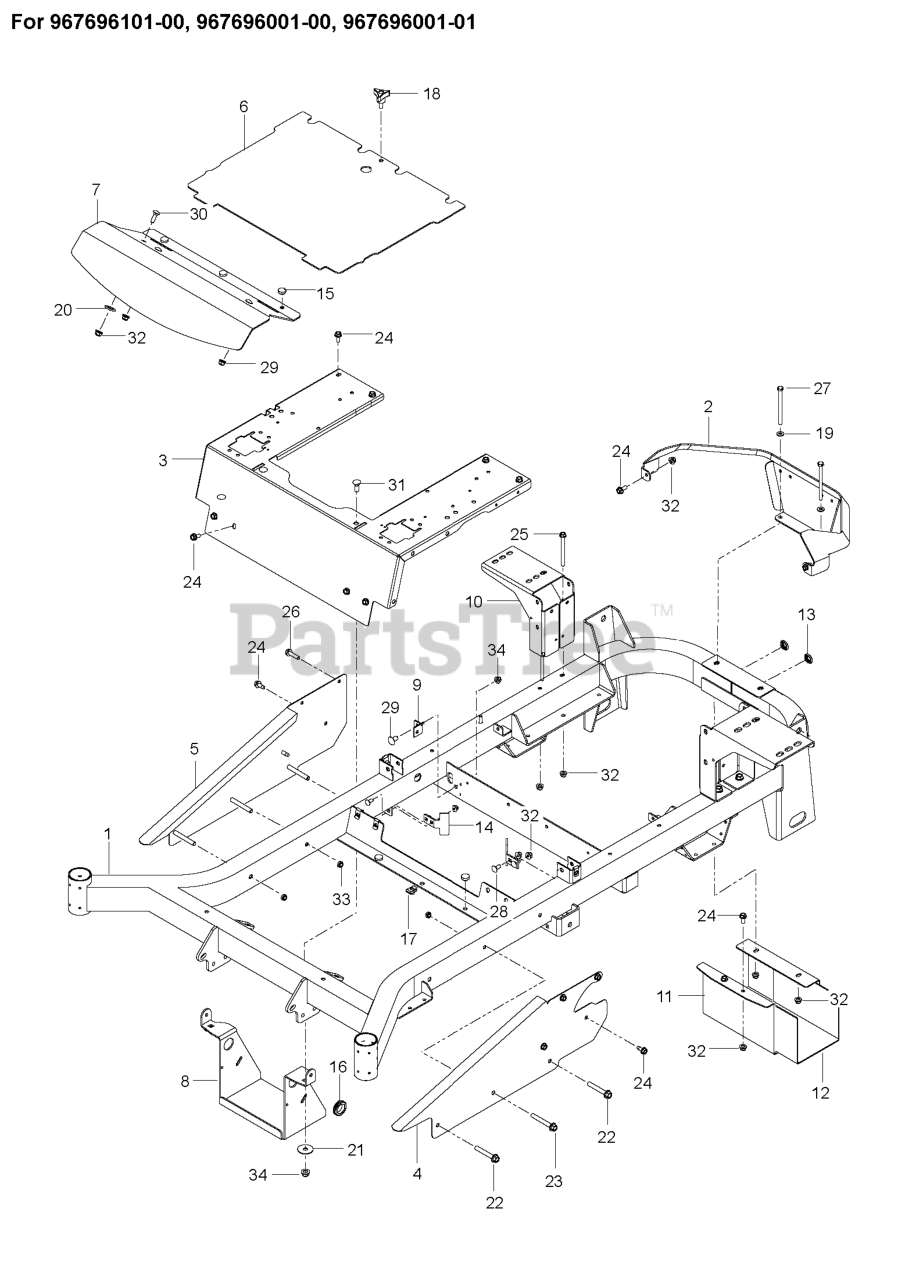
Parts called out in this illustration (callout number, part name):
1	KIT.FRAME.W/DECALS.X668
2	GUARD.PNT.REAR.MZ.GRAY
3	SUPPORT.PNT.SEAT.CONTROL.ORNG
4	SIDE.LT.ORANGE
5	SIDE.RT.ORANGE
6	PLATE, FLOOR W/DECALS
7	PLATE, FOOTREST
8	BRACKET.PNT.BATTERY.BLK
9	BRACKET.DAMPENER.BLACK
10	MOUNT, TANK, ZT BLK
11	SHIELD.MUFFLER.BLACK
12	HEAT SHIELD
13	CAP.PLUG.BP-1.BLACK
14	STOP, DECK, EZ+
15	GROMMET, BUMPER
16	RUBBER GROMMET
17	U-CLIP 5/16-18 NUT RETAINER
18	KNOB W/STUD
19	WASHER
20	WASHER 1/2" FLAT
21	WASHER.13/32X1-1/2X16GA
22	HHFS 3/8-16 X 2.5 GR 5 ZD
23	HHFS 3/8-16 X 2-3/4 GR5 ZD
24	HHFS 5/16-18 X 3/4
25	BOLT.HEX.FLNG.5/16-18X3.75
26	HHFS 5/16-18 X 1.25 TPBLT GD 5
27	HCS 5/16C X 4
28	BOLT 5/16C X 3/4" CARRIAGE
29	RHSNB 3/8-16 X 3/4 GR 5 BLK ZN
30	RHSNB 5/16C X 1
31	RHSNB 3/8C X 1
32	5/16-18 NYLOC FLANGE NUT
33	NUT HEX 3/8-16 NYLON, THIN
34	NUT 3/8-16 HEX FLG NYLOC ZD
